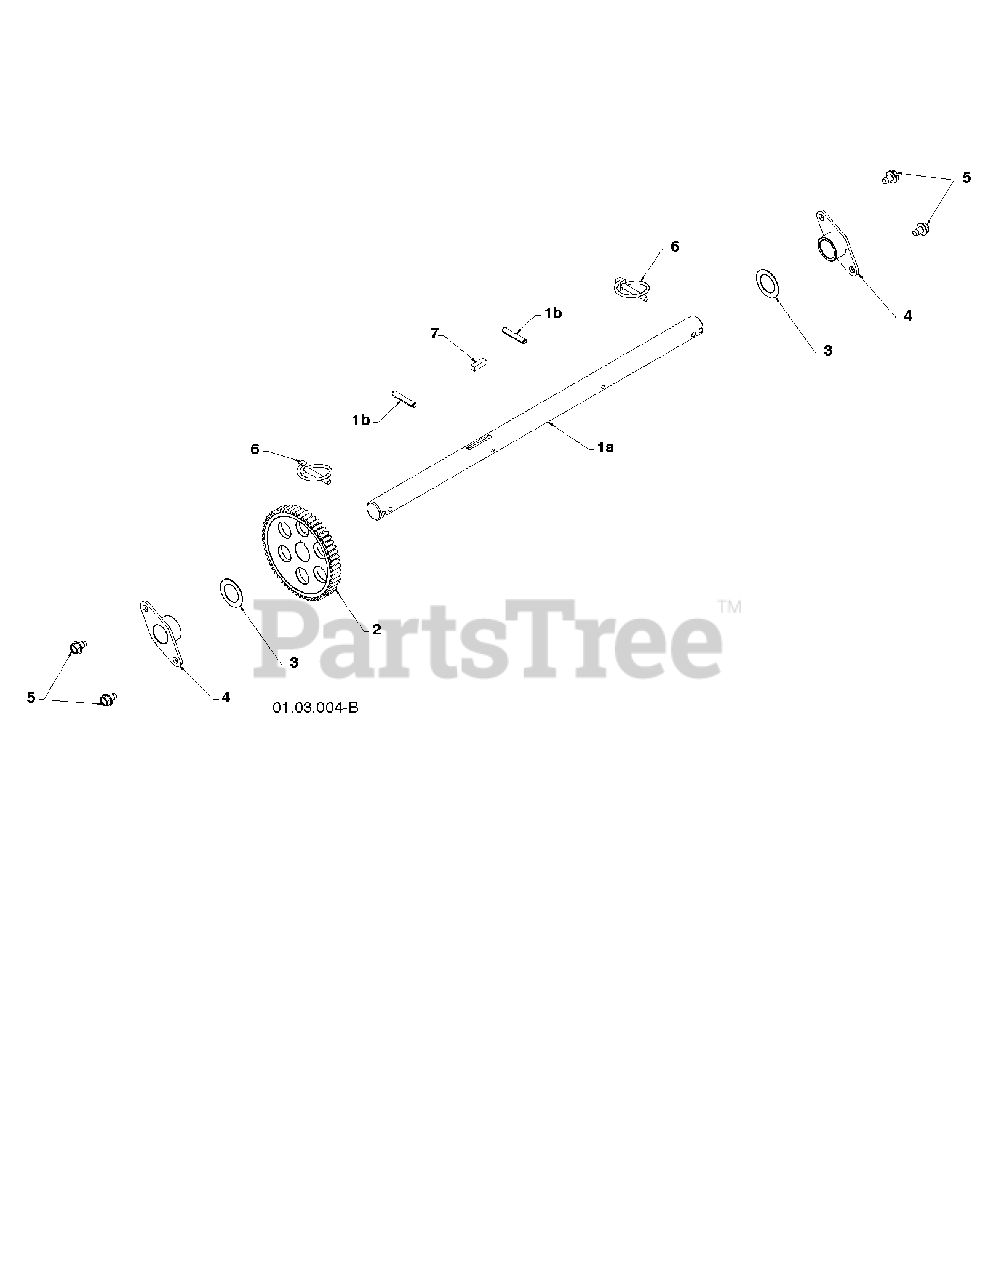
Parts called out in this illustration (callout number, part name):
1	AXLE.SHAFT.ASM.W/ROLPIN.
1A	SHAFT.AXLE.16".SNOW
1B	PIN.ROLL.3/16
2	GEAR, AXLE (58T)
3	WASHER TRUST 1"
4	BEARING, AXLE
6	PIN KLIK, 1/4
7	KEY, SQUARE 1/4 X .875
